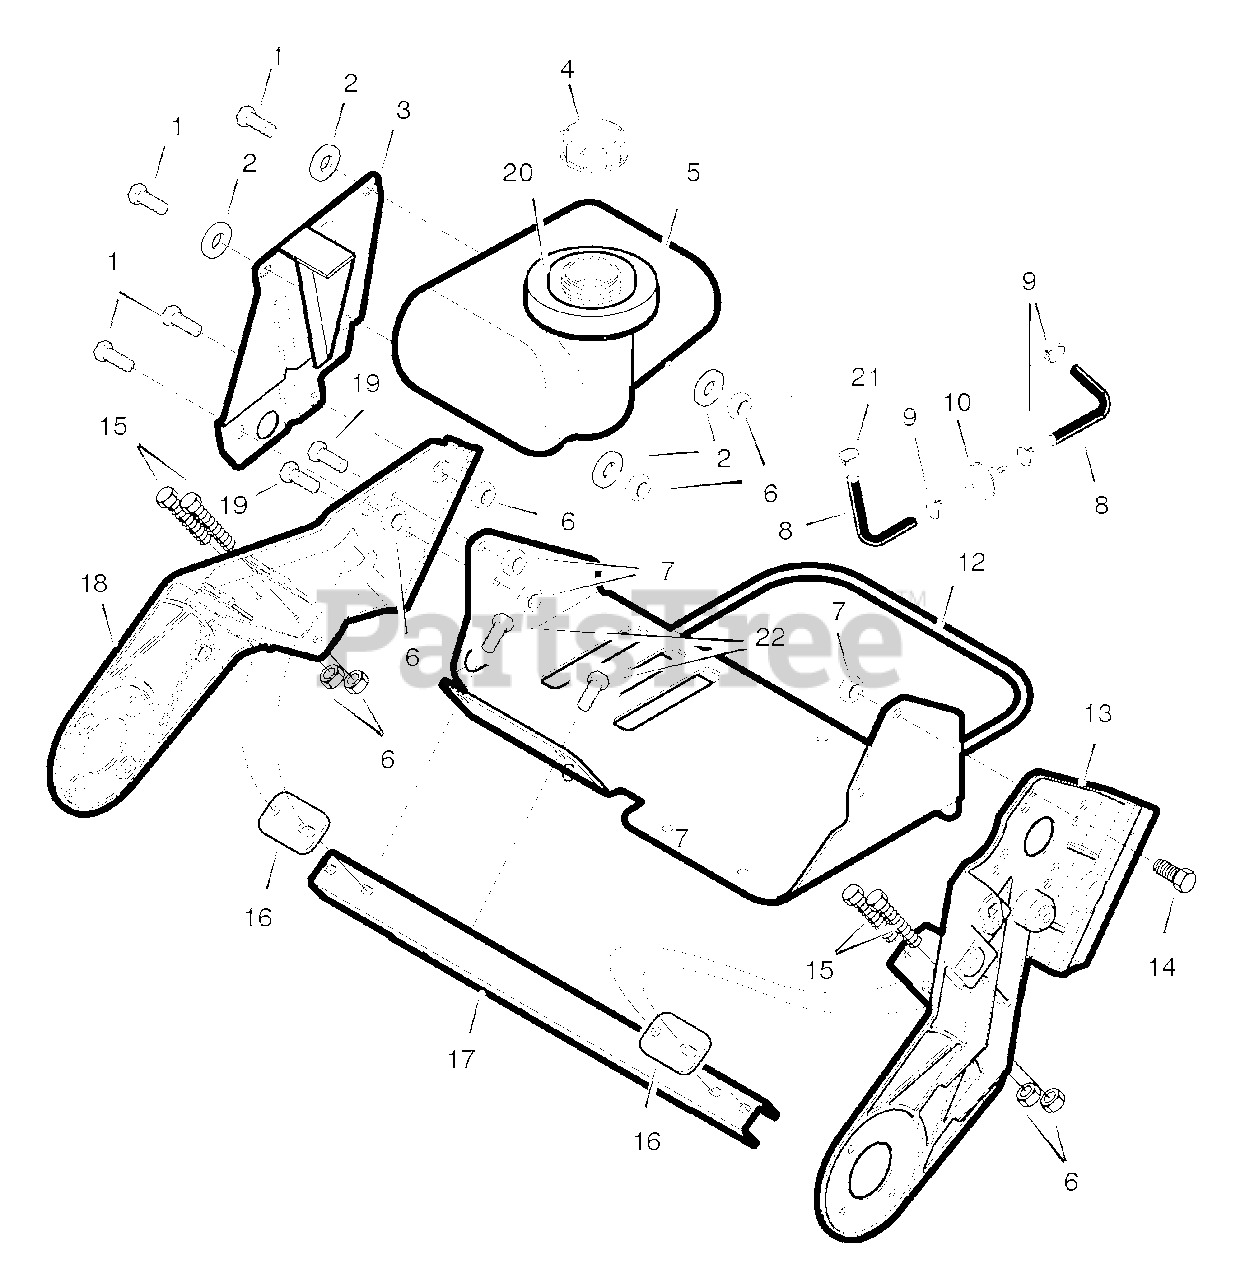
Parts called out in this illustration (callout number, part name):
1	Screw 1/4-20 x .75
2	Washer
3	Bracket, Fuel Tank
4	Cap, Fuel Tank
5	Tank, Fuel
6	Nut, Hex 1/4-20
7	Nut, Hex 5/16-18
8	HOSE, FUEL 12 INCHES
9	Clamp, Fuel Line
10	Filter, Fuel Line
11	Tubing, Fuel LIne
12	Cradle Assy, Engine
13	Frame, LH
14	Screw, 5/16-18 x 0.63
15	Screw, 1/4-20 x 2.00
16	Plate, Support
17	Support, Frame
18	Frame, RH
19	Screw, 5/16-18 x 0.75
20	Ring, Foam
21	Clamp, Screw Type
22	Screw 1/4-20 x .625
